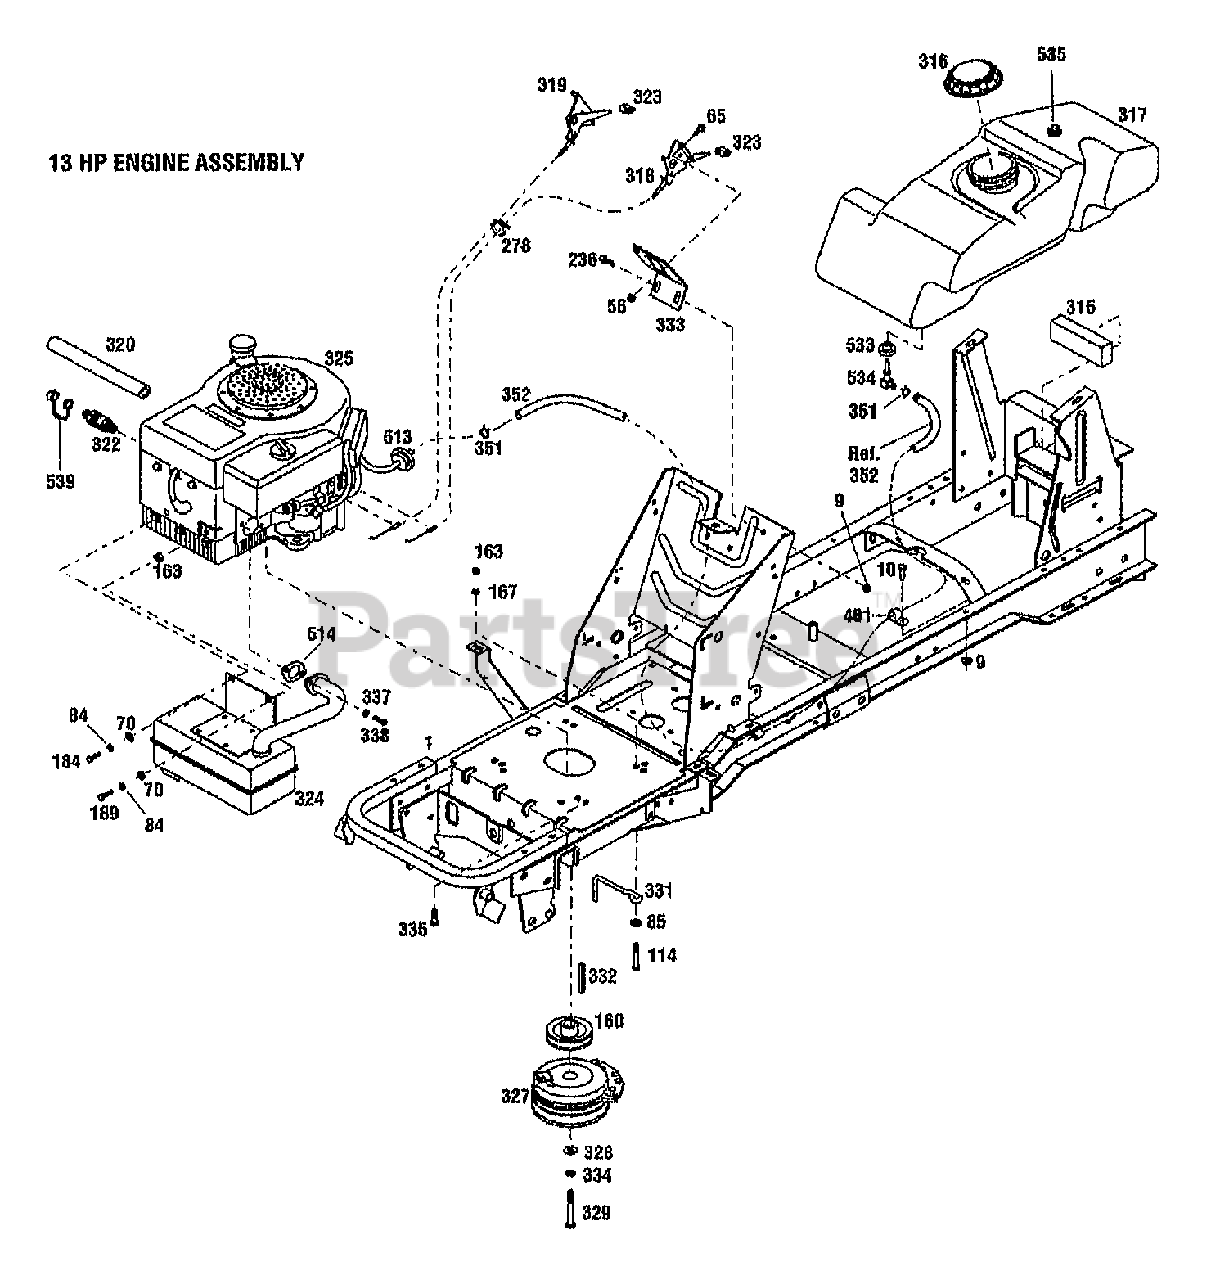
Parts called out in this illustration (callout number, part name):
1	ASSM-FRAME LTX
9	SCR-HH 5/16-18X1.0 G5 ZP
10	SCR-HHC 5/16-18X.75 GR 5 ZP
56	NUT-HF/LK 1/4-20 ZP
65	SCR-HH 1/4-20X.625
70	WASHER-FLAT 1/4 SAE
84	WASHER-LK .25 ZP
85	WASHER-FLAT 3/8 SAE
114	SCR-THRD FRM 3/8-16X1.50
160	PULLEY-ENGINE
163	NUT-HEX 3/8-16 ZP
167	WASHER-LK .375 @ DEPL
184	SCR-HH 1/4-20 X .875
189	SCR-HH 1/4-20X1.25
236	SCR-HFLK 5/16-18X.75 ZP
278	TIE-CABLE NYLON BLACK
315	PAD-FUEL TANK
316	CAP-FUEL
317	TANK-FUEL
318	CONTROL-THROTTLE
319	CONTROL-CHOKE
320	HOSE-OIL DRAIN
322	ASSM-OIL VALVE
324	MUFFLER
325	ENGINE, 13HP, MODEL 28M707
327	CLUTCH-ELECTRIC
328	WASHER-SPEC 1.42X.468X.25 ZP
329	SCR-HH 7/16-20X3 G5 ZP
331	CLUTCH-RETAINER
332	KEY-.25 SQ X 1.5
333	BRKT-MOUNTING CONTROL
334	WASHER-LK .438 ZP
335	SCR-HH 3/8-16X1.0 THDFM
337	WASHER-LOCK
338	SCR-HXSKT 5/16-18X.75 BO
351	CLAMP-HOSE
352	LINE-FUEL
401	CLAMP-WIRE
513	FILTER-FUEL
514	MUFFLER GASKET
533	BUSHING-RUBBER
534	ELBOW-90 DEG (FUEL LINE)
535	VENT-FUEL TANK
539	CAP-OIL DRAIN
